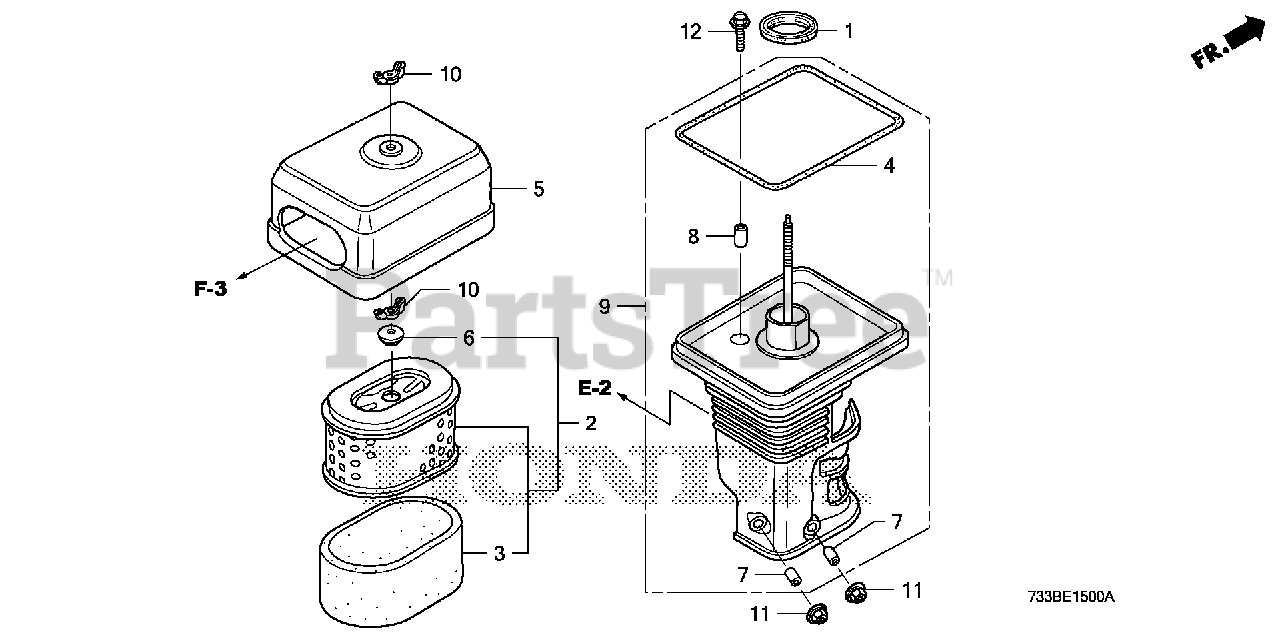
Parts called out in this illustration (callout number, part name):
1	GASKET, ELBOW
2	ELEMENT, AIR CLEANER (DUAL) Use up to Engine SN 2115700.
2	ELEMENT, AIR CLEANER (DUAL)
3	FILTER (OUTER)
4	GASKET, AIR CLEANER COVER
5	COVER, AIR CLEANER
6	GROMMET, AIR CLEANER
7	COLLAR, AIR CLEANER Use from Engine SN 1786085.
8	COLLAR B, AIR CLEANER
9	ELBOW, AIR CLEANER
10	WINGNUT, TOOL BOX SETTING
11	NUT, FLANGE (6MM)
12	BOLT, FLANGE (6X20)
